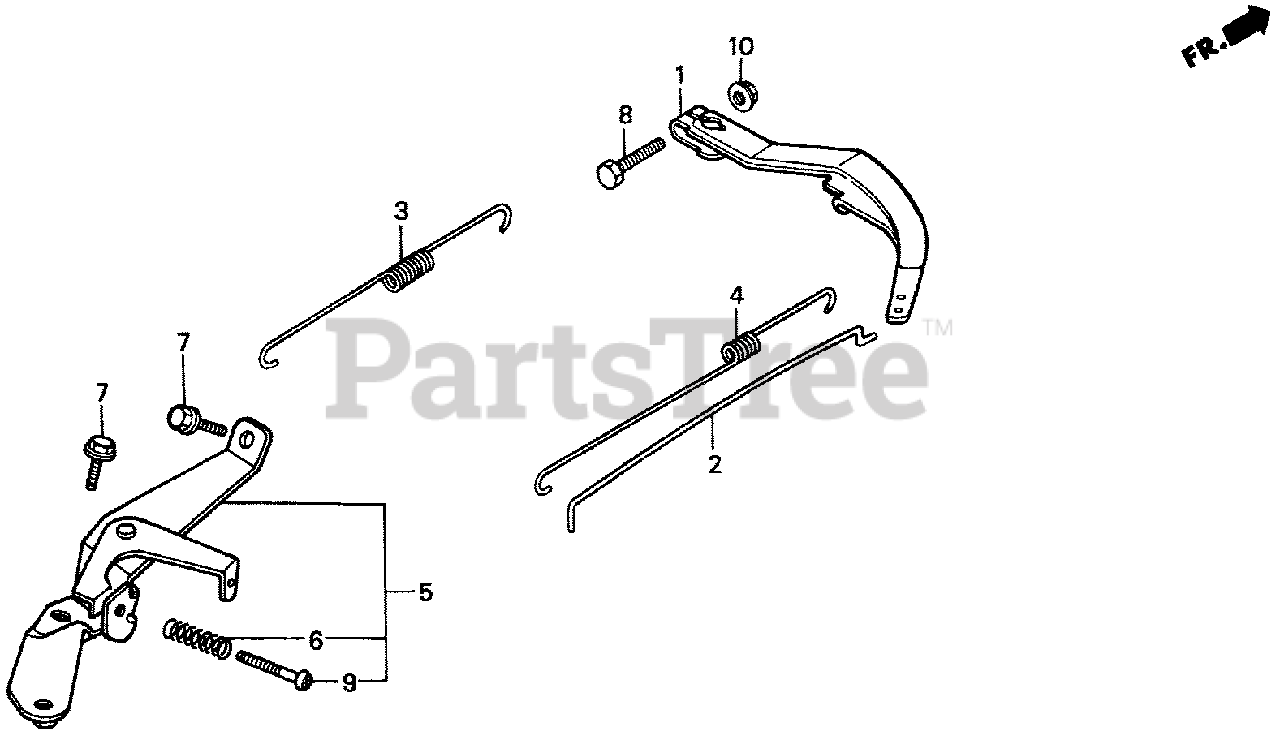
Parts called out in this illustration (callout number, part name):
1	ARM, GOVERNOR
2	ROD, GOVERNOR
3	SPRING, GOVERNOR
4	SPRING, THROTTLE RETURN
5	CONTROL ASSY.
6	SPRING, CONTROL ADJUSTING
7	BOLT, FLANGE (6X12) (CT200)
8	BOLT, GOVERNOR ARM
9	SCREW, PAN (5X35)
10	NUT, FLANGE (6MM)
